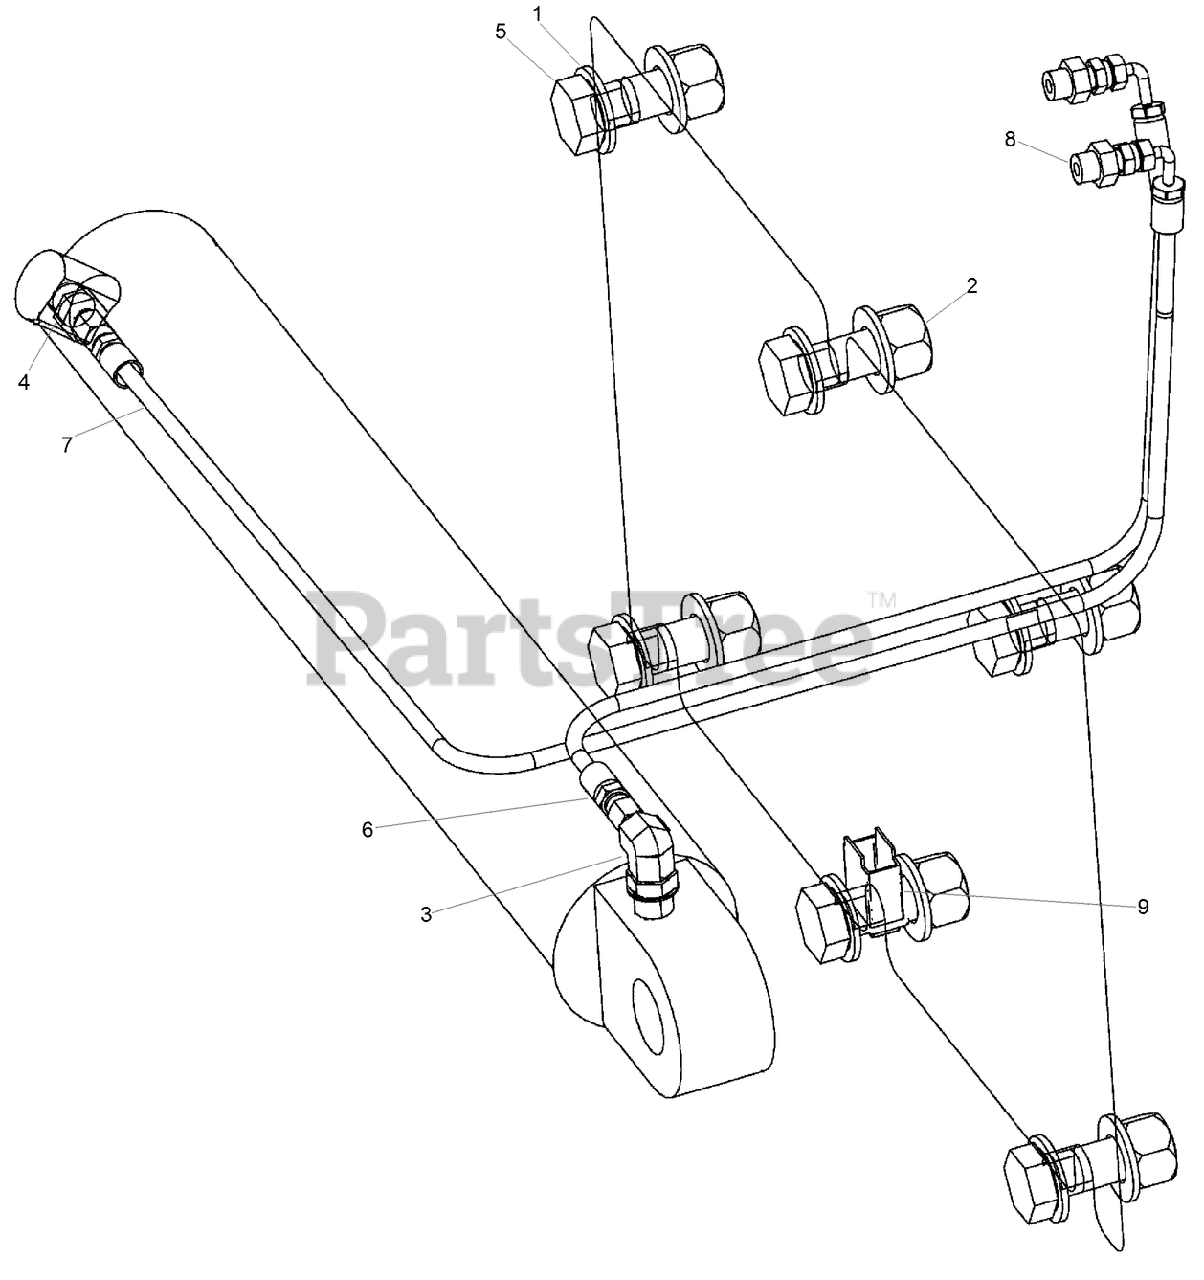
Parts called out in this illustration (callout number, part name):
3	FITTING-ELBOW, 90 DEG
4	CONNECTOR
6	HOSE ASSEMBLY - Hydraulic
7	HOSE ASSEMBLY - Hydraulic
8	CONNECTOR
9	SWITCH-ROCKER, 2 POLE
